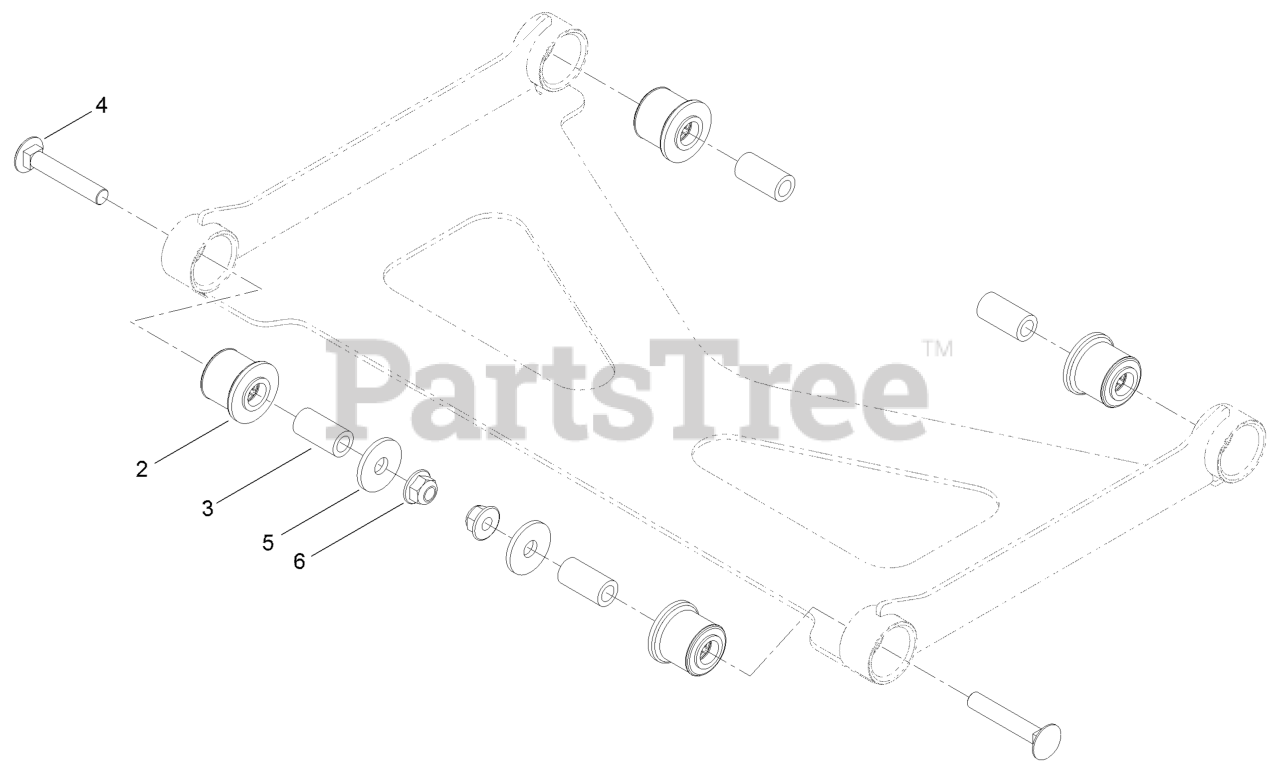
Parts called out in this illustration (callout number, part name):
2	BUSHING-RUBBER, SUSPENSION
4	Bolt-Carriage 3/8-16 X 2 1/4
5	WASHER
6	NUT-HF, NI
